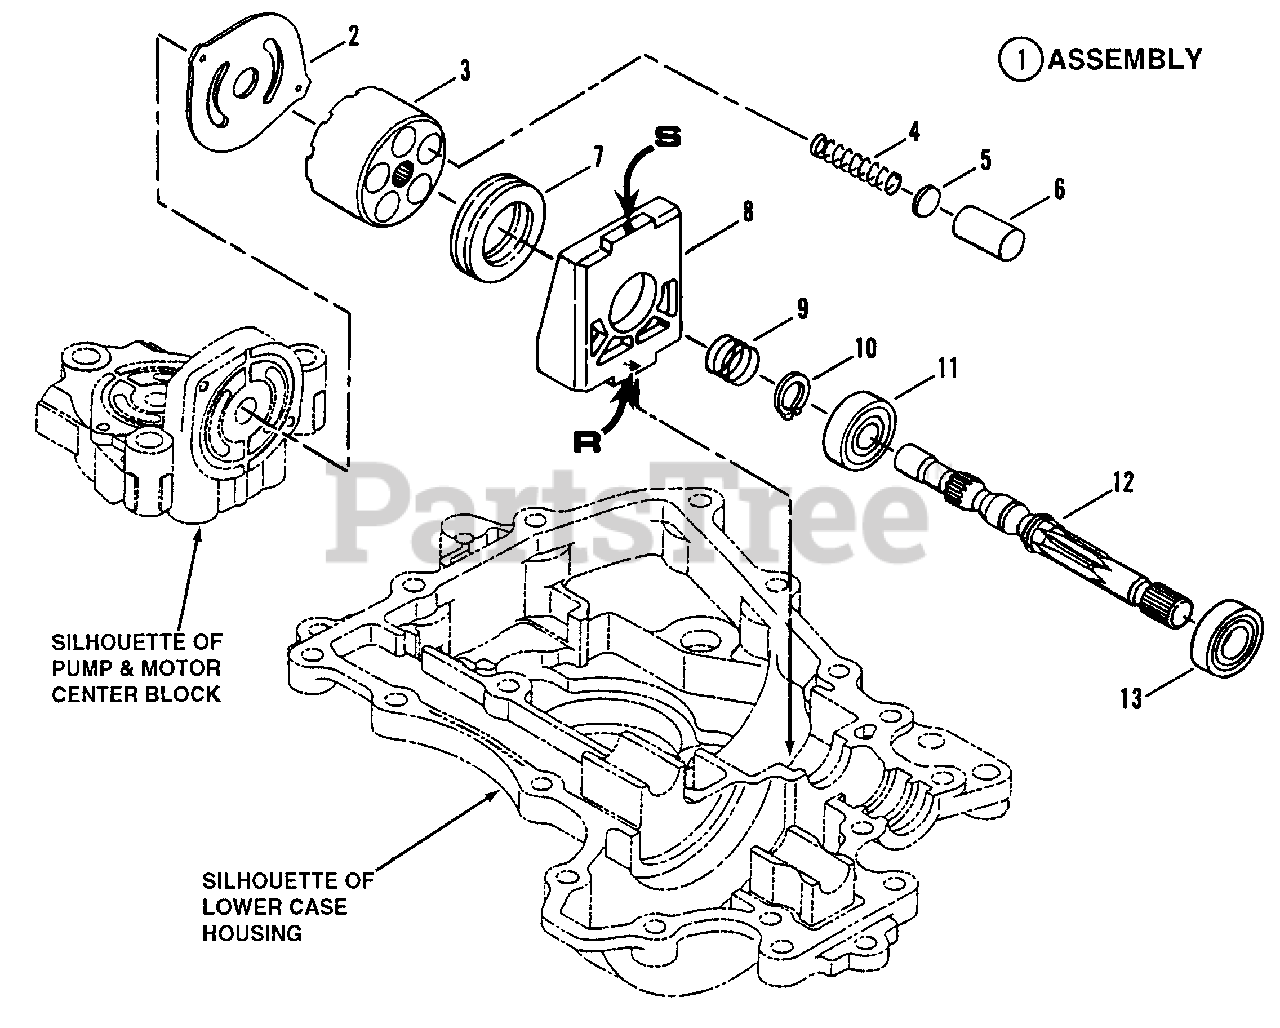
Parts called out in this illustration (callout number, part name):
1	ASSEMBLY, Cylinder Block
3	CYLINDER BLOCK, Motor
4	SPRING, Piston
5	WASHER, Pump Piston
6	PISTON, Cylinder Block
7	BEARING, Motor Swashplate
8	HOUSING, Motor Fixed Swashplate
10	SNAP-RING
11	BEARING, Ball
12	SHAFT, Motor Output (K50)
13	BEARING, Ball
